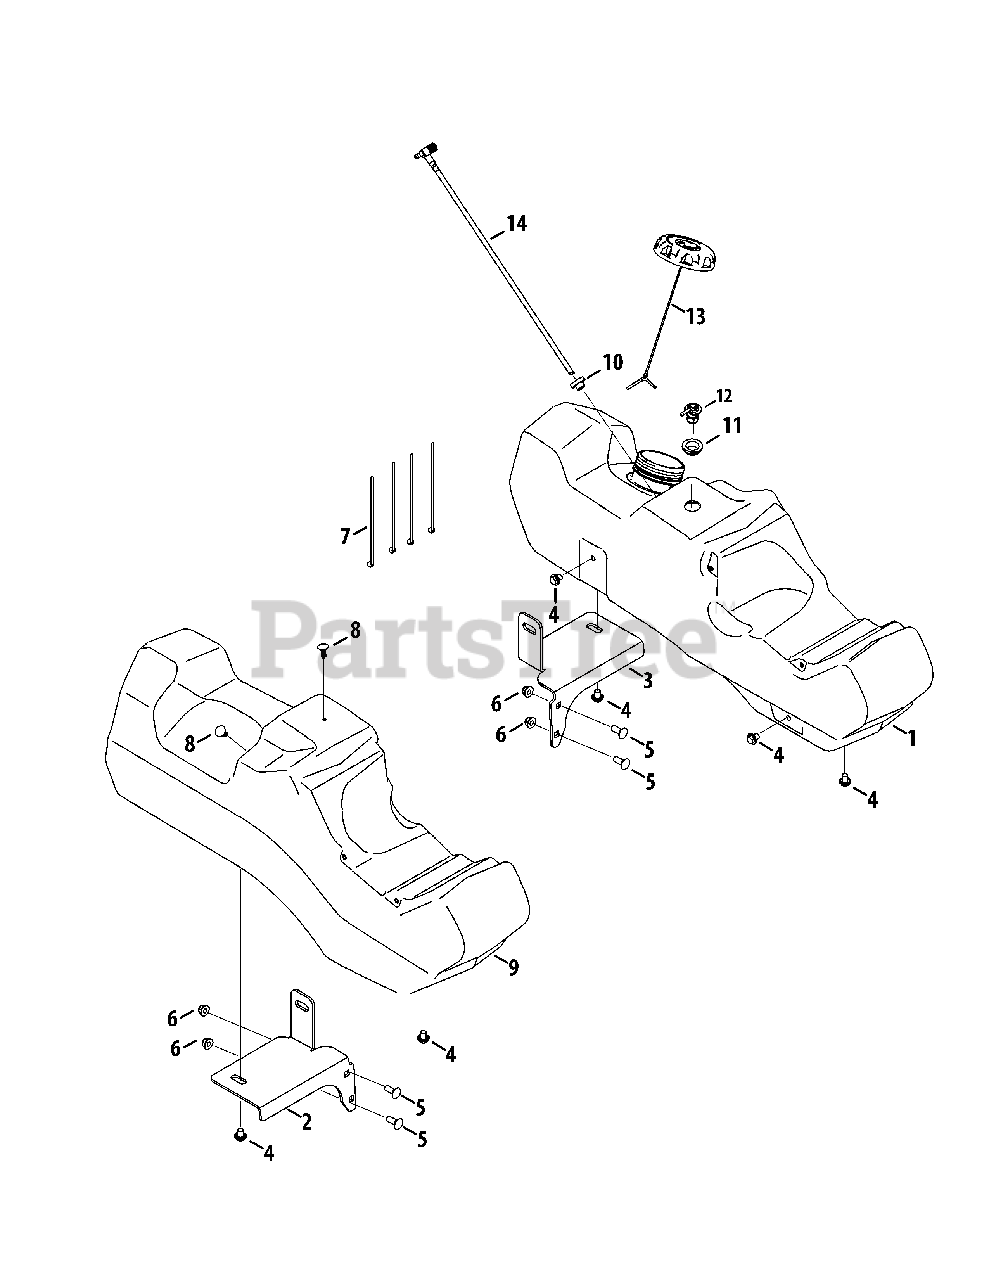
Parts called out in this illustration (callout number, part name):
1	Fuel Tank Assembly, LH
2	Rear Fuel Bracket, RH
3	Rear Fuel Bracket, LH
4	Hex Cap Screw, 3/8-16 x .500
5	Carriage Bolt, 3/8-16 x .500
6	Nut, 3/8-16, Flangelock
7	Cable Tie
8	Clip, .250 Dia.
9	Console, RH
10	Fuel Tank Grommet
11	Grommet, .755 x .955 x .55
12	Fuel Rollover Valve
14	Fuel Pickup Valve
